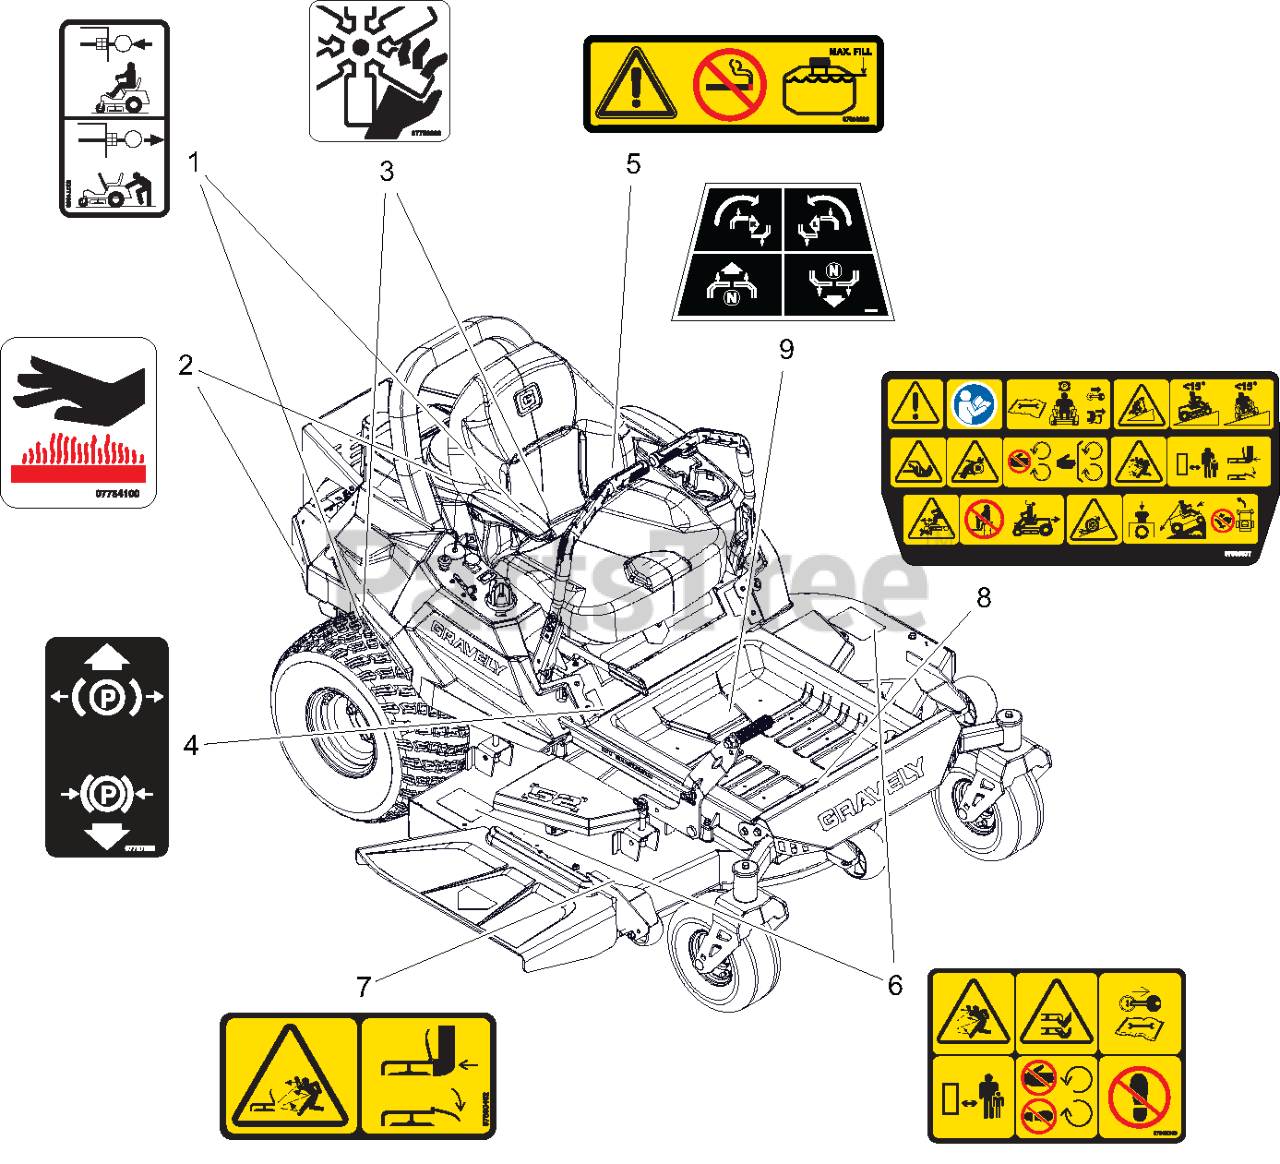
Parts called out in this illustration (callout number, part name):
1	DECAL, TRANSMISSION DISCONNECT
2	DECAL, HOT SURFACE
3	DECAL, DANGER FAN
4	DECAL, PARKING BRAKE LEVER
5	DECAL, FUEL WARNING
6	DECAL, SAFETY - MOWER DECK
7	DECAL, SAFETY - DECK GUARDING
8	DECAL, MAIN SAFETY
9	DECAL, STEERING
